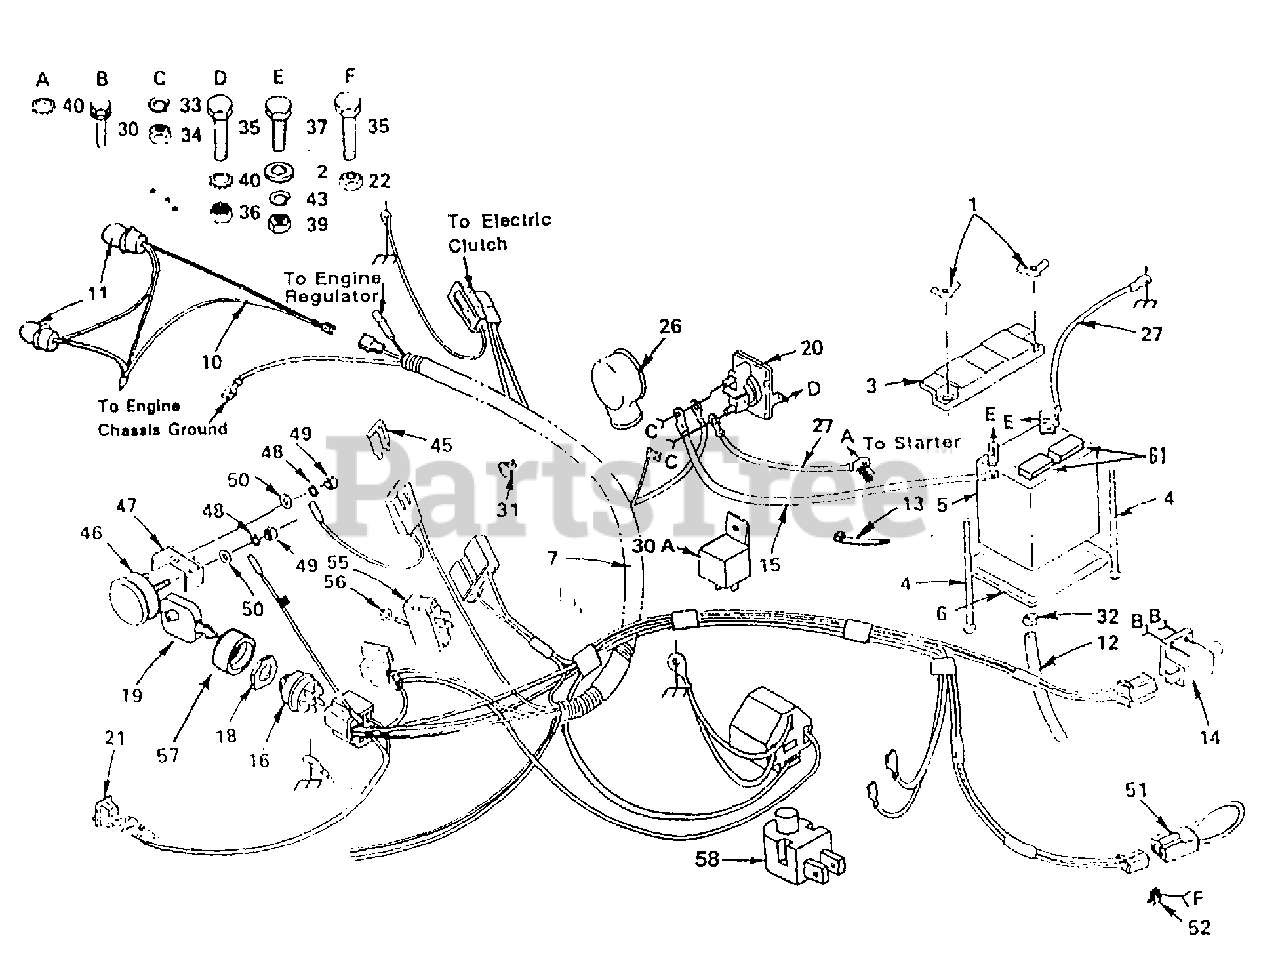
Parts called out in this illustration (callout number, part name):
1	Wing Nut 1/4-20
2	Washer 9/32 x 5/8 x 16 Ga
3	Guard-Terminal
4	Battery Bolt (Bolt-Carriage,Rd. Hd. Sq. Neck 1/4-20 x 7-1t21
5	Battery
6	Battery Tray
7	Harness - Ignition
10	Harness-Light Socket
11	Bulb-Light
12	Tube-Battery Tray
13	Cable Tie
14	Switch - Interlock - Clutch
15	Cable-Battery (Battery to Solenoid)
16	Ignition Switch
18	Nut- Ignition
20	Diode Asm.Zener
21	Switch-Light
26	Terminal Cover
27	Cable-Battery (Battery to Ground)
30	Screw-Tap. Hex Hd. No.10-24 UNC
31	Clip-Fuel Line
32	Clamp-Hose
40	Washer-Lock 1/4 Ext. Tooth
45	Fuse-30 Amp.
51	Loop-Wire Tiller Attachment
52	Clip- Insulated
55	Switch PTO
57	Bezel, Ignition
58	Switch.Plunger
61	Caps, Battery Set
62	Light Package
63	Decal.Battery
64	Bolt.Fin.Hex 1/4-20 UNC x 1/2 G
